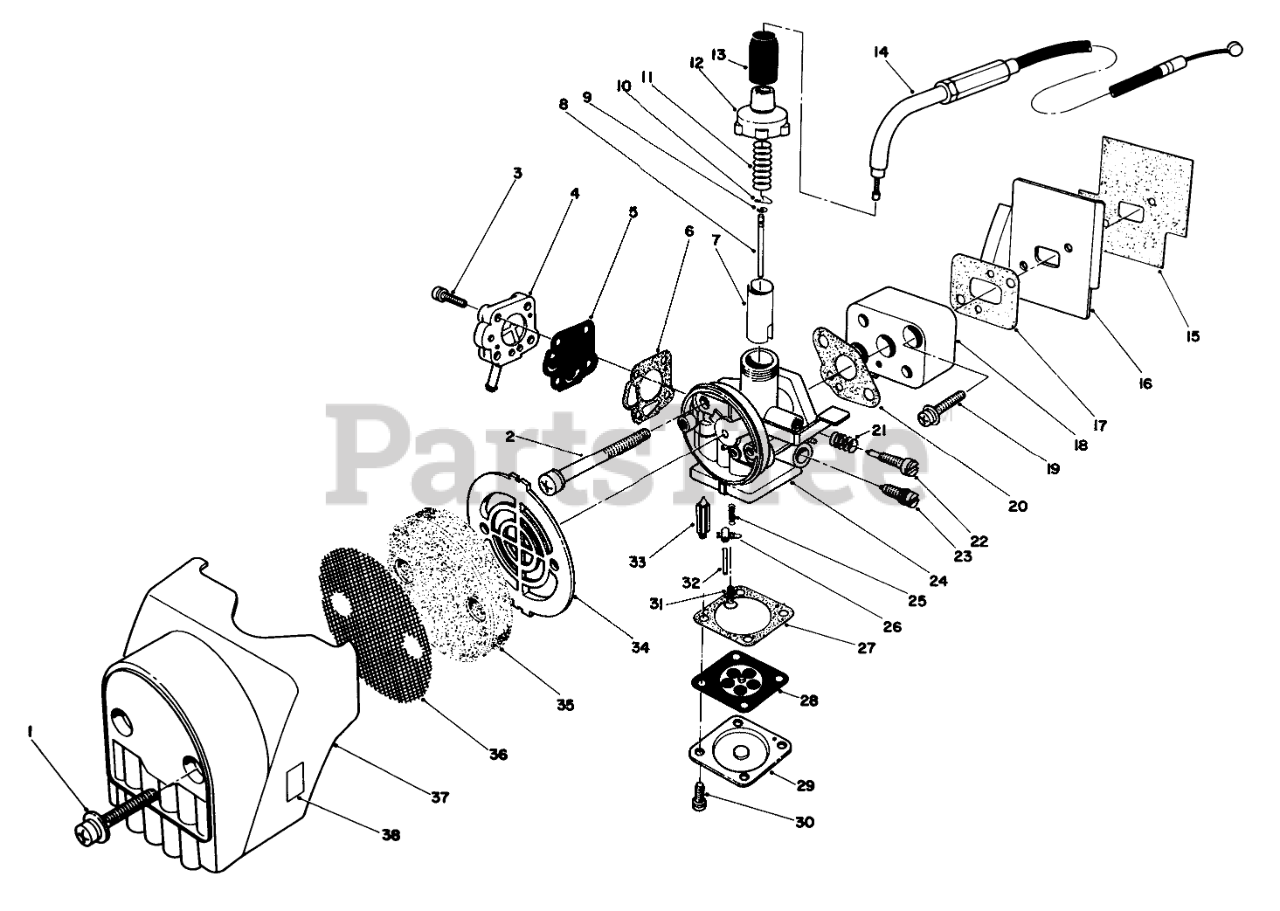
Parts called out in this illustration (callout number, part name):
1	Screw
2	SCREW W/ WASHER
3	SCREW W/ WASHER
4	PUMP COVER
5	PUMP DIAPHRAGM
6	PUMP COVER GASKET
7	Valve-Throttle
8	NEEDLE JET
9	Retainer
10	NEEDLE CUP
11	SPRING
13	AIR SEAL
14	Wire-Throttle
15	Gasket
16	Plate
17	INSULATOR GASKET
18	Insulator
19	Screw
20	CARB. GASKET
21	ADJ. SCREW SPRING
22	Screw-Adjusting
23	MAIN NEEDLE
24	Carburetor Assembly (Incl. Ref. #3-13, 21-23, & 25-33)
25	VALVE SPRING
26	FLOAT ARM
27	DIAPHRAGM GASKET
28	MAIN DIAPHRAGM
29	DIAPHRAGM COVER
30	SCREW W/ WASHER
31	FLOAT SCREW
32	FLOAT PIN
33	FLOAT VALVE
35	ELEMENT
36	SCREEN
37	CLEANER COVER
38	CHOKE LABEL
